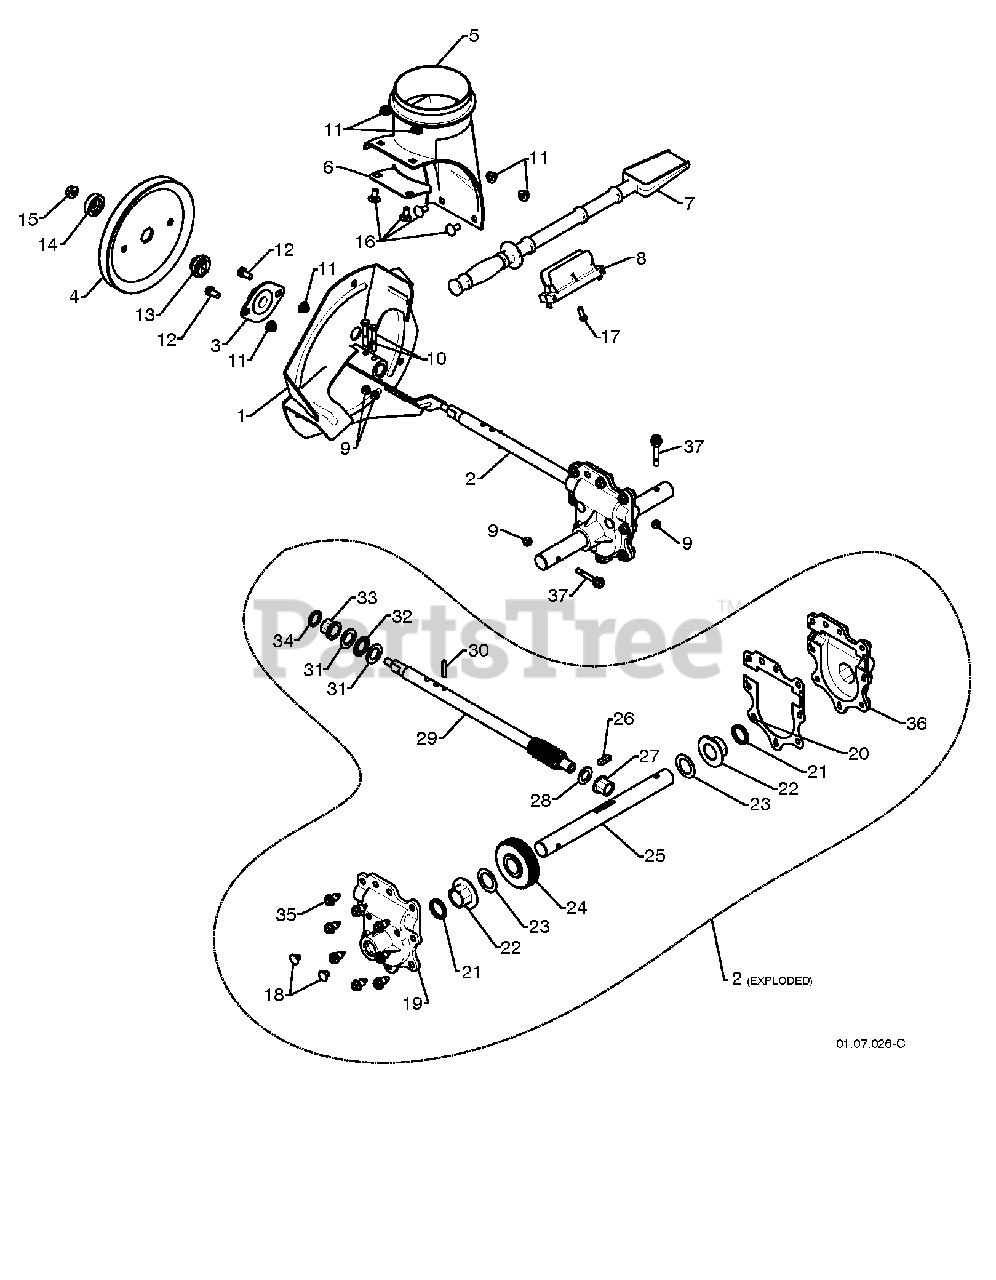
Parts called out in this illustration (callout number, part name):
1	IMPELLER ASSY
2	GEARBOX.ASM.AUGER.D-SHAFT
3	BEARING FLANGE
4	PULLEY.FLANGE.IMPELLER
5	BASE DISCHARGE CHUTE
6	BRACKET, CORNER DISCHARGE
7	CLEAN OUT TOOL
8	CLIP.CLEANOUT.TOOL
9	LOCKNUT
10	SCREW.HEX.HD1/4-20X
11	SCREW.HEX.HD1/4-20X
12	BOLT, HEX HEAD 5/16-18
13	HUB.IMP.PULLEY.D-SHAFT
14	SLEEVE.IMP.PULLEY.D-SHAFT
15	NUT LOCK FLG 3/8-16 UNC
16	BOLT.CARRIAGE.5/16-18X
17	SCREW.HWH.13-16-5.8.BZP
18	CASE PLUG
19	GEAR.BOX.COVER.RIGHT.SIDE
20	GASKET.GEAR.BOX
21	OIL SEAL
22	FLANGE BUSHING-1"
23	WASHER TRUST 1"
24	WORM GEAR
25	AUGER SHAFT
26	KEY, SQUARE 1/4 X .875
27	FLANGE BUSHING-5/8
28	WASHER, THRUST 5/8
29	SHAFT.IMPELLER.D-SHAFT
30	PIN, ROLL 3/16 X 1-1/8
31	WASHER, THRUST 3/4
32	BEARING TRUST 3/4
33	BUSHING, FLANGE 3/4
35	HEX SCREW-5/16 X 3/4
36	GEAR.BOX.COVER.LEFT.SIDE
37	BOLT, SHOULDER SHEAR
